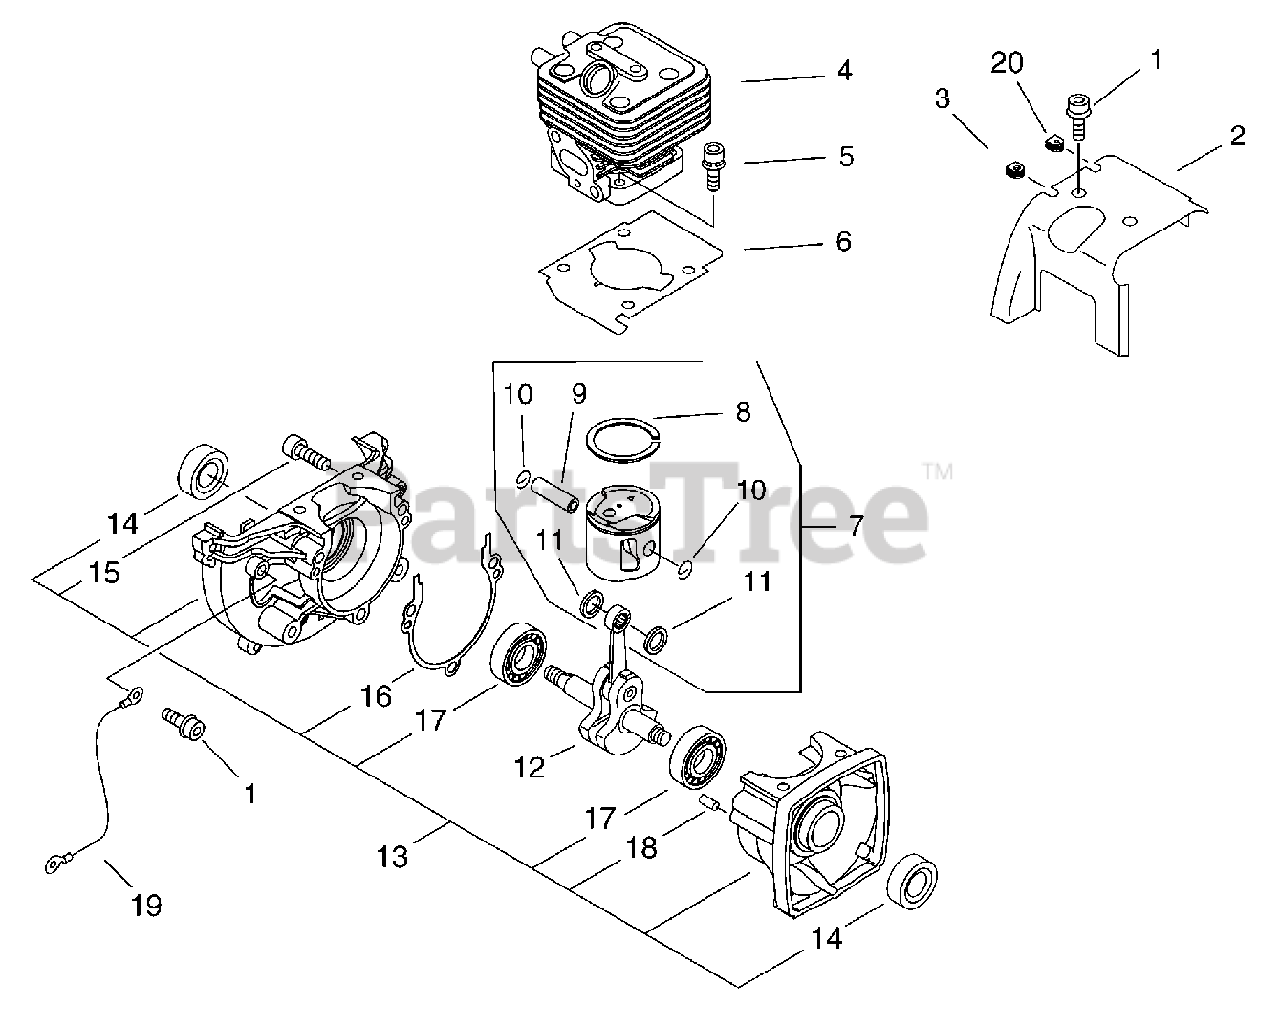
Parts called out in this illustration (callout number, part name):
1	SCREW - 5X8
2	SHIELD, CYLINDER
4	CYLINDER
5	SCREW - 5X25
6	GASKET, CYLINDER
7	PISTON KIT
8	RING, PISTON
9	PIN, PISTON
10	RING, RETAINING
11	SPACER, PISTON
12	CRANKSHAFT ASSY
13	CRANKCASE KIT
14	SEAL, OIL
15	SCREW - 5X28
16	GASKET, CRANKCASE
17	BEARING, BALL - 6201
18	PIN - LOCATING
19	LEAD - GROUND
